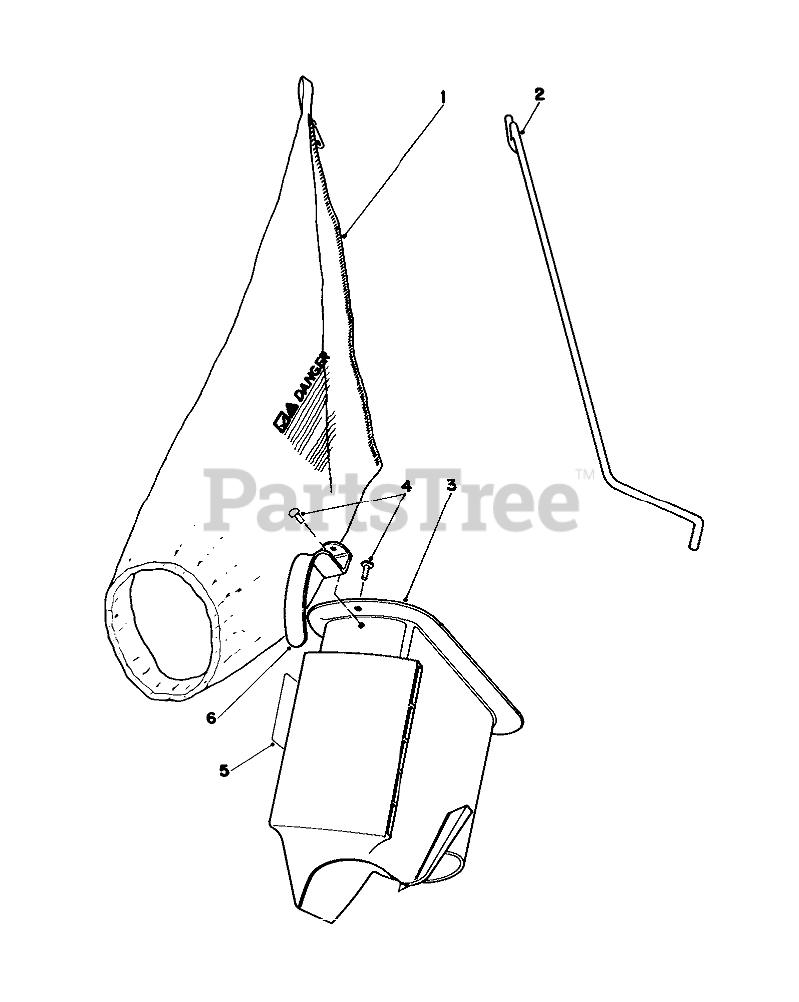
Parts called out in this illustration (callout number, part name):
1	BAG REPLACMNT44-0540
2	BAG ROD
3	Grass Chute (Incl. Ref. #4&6)
4	RIVET 3/16 X 7/16
5	BAG CHUTE DECAL
6	HANDLE-GRASS CHUTE
